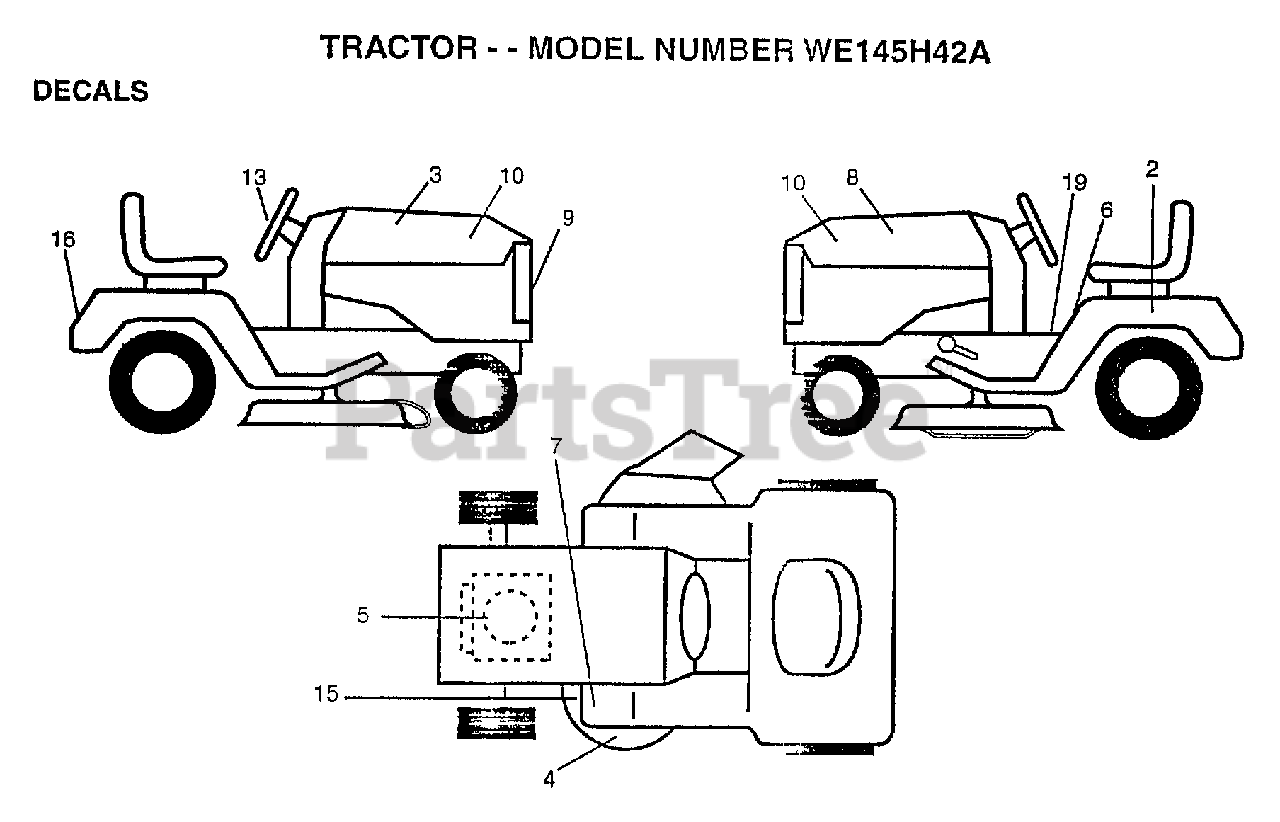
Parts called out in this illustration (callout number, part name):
2	DECAL.BATRY.3-3908
3	"DECAL HOOD,RH"
5	DECAL, ENGINE
6	"DECAL DANGER,FEND"
8	DECAL HOOD LH
9	"DECAL GRILLE,LENS"
10	"DECAL.PANEL,SIDE"
13	"DECAL INS,STRG WH"
15	DECAL
16	DECAL-FENDER
19	"DECAL INST,SADDLE"
